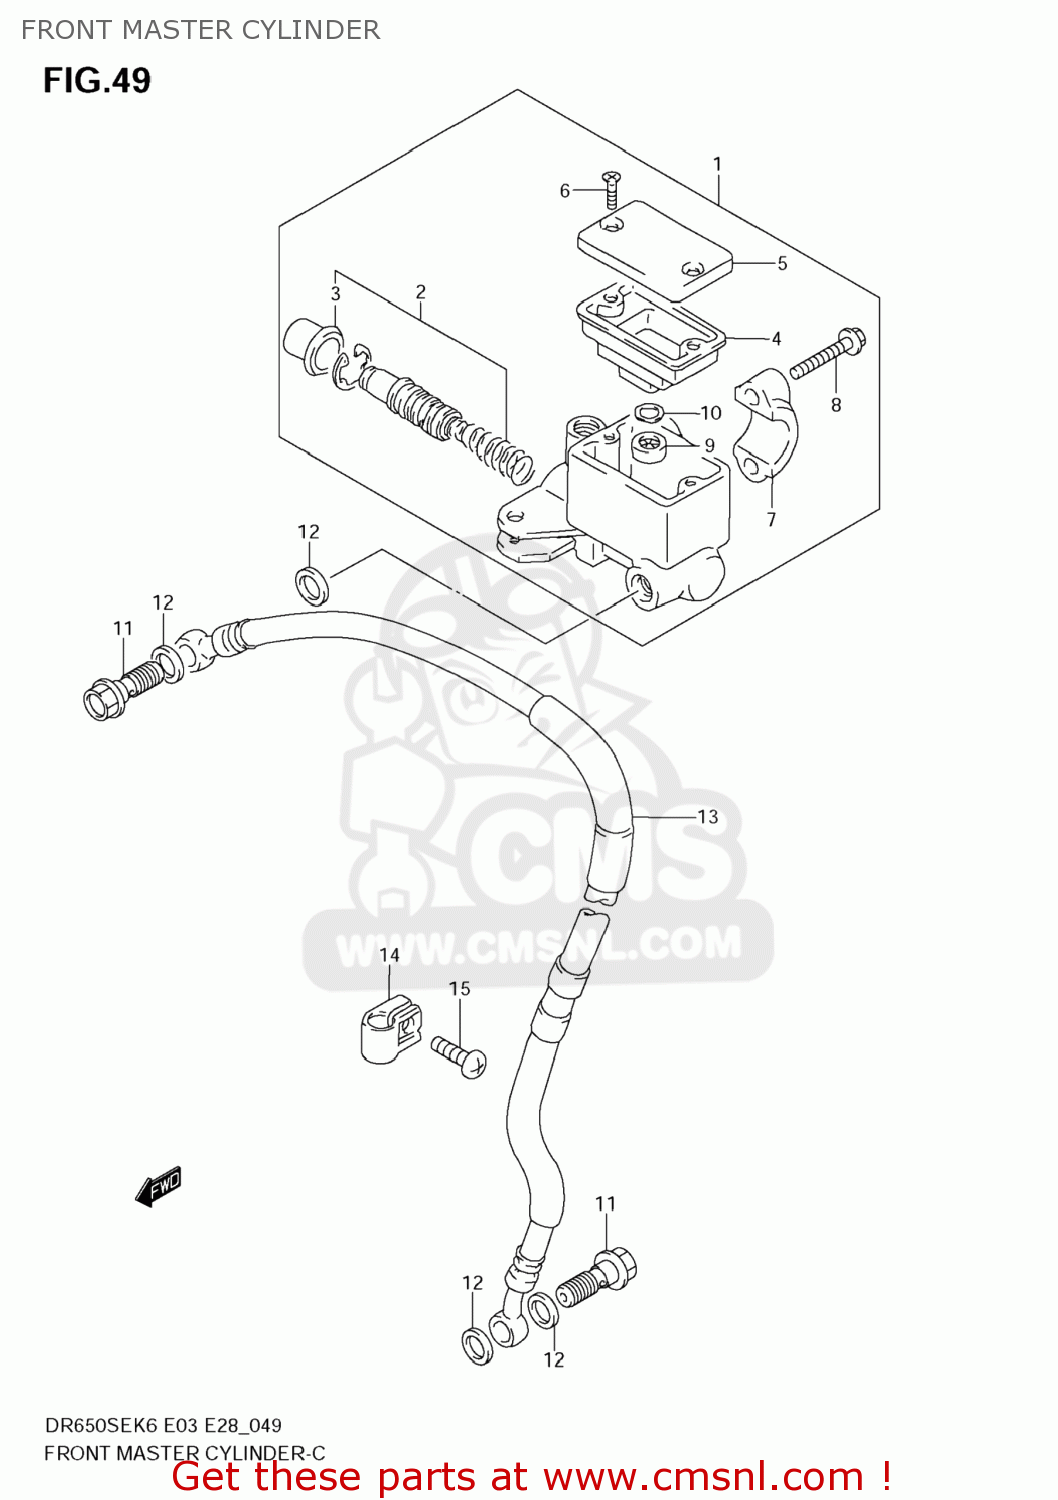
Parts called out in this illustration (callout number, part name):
1	CYLINDER ASSY,FR MASTER
2	PISTON/CUP SET
3	BOOT
4	DIAPHRAGM
5	CAP
6	SCREW
7	HOLDER
8	BOLT(6X22)
9	SEPERATOR
10	PLATE
11	BOLT UNION
12	WASHER(10X15X1.5)
13	HOSE,FR BRAKE
14	CLAMP,BRAKE HOSE
15	SCREW
